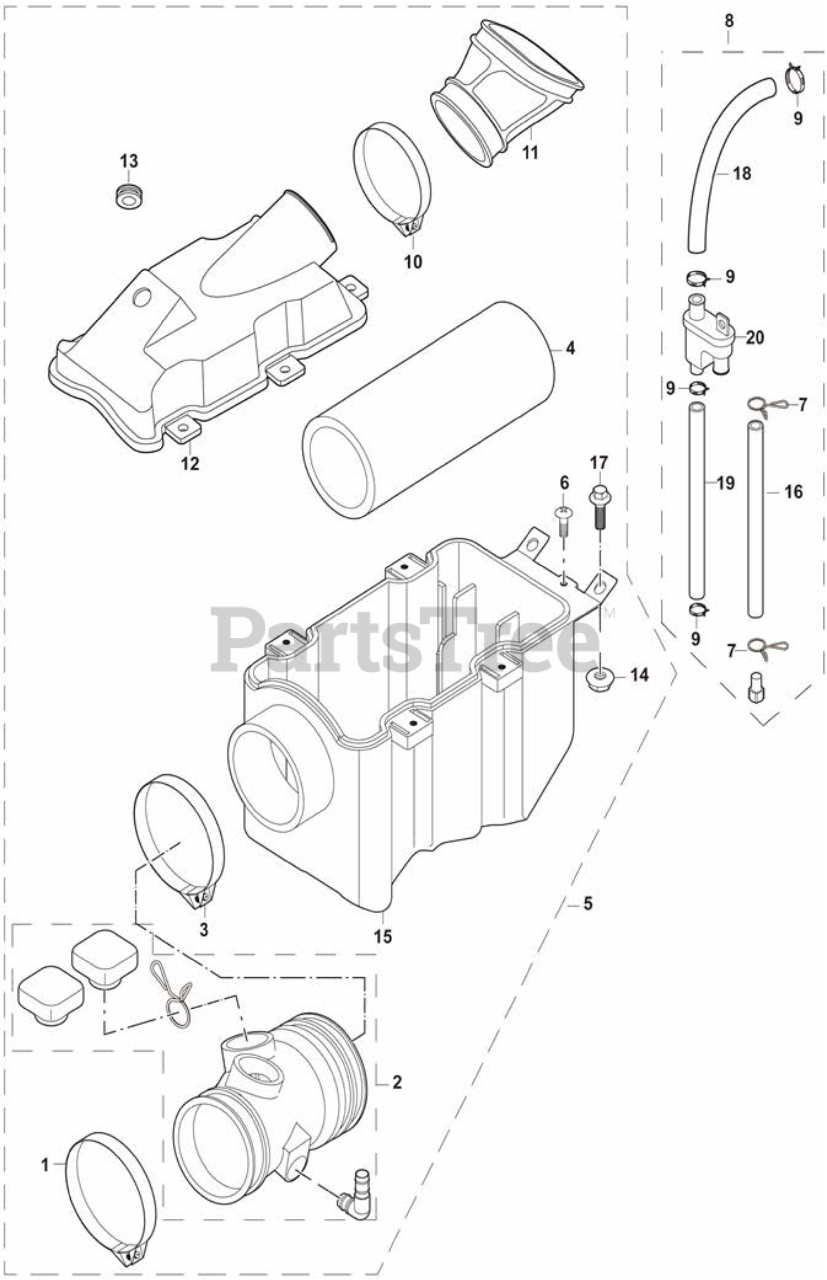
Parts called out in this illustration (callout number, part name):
1	Screw Hoop J
2	Second Intake Pipe
3	Screw Hoop J
4	secondary filter element
5	Secondary air filter
6	Cross Plate Head Tapping Screw M5X12
8	Oil&Air Separator
9	Elastic hoop H
10	Screw Hoop J
11	Secondaryary Inlet Pipe
12	Secondary filter cap
13	Shock pad?round card slot 9X3
14	Hexagon Flange Nut M8
15	secondary filter
16	Exhaust return tube
17	Hexagon Flange BoltM8X20
18	EGR Tube I
19	EGR Tube III
20	Oil-gas Separator boby
